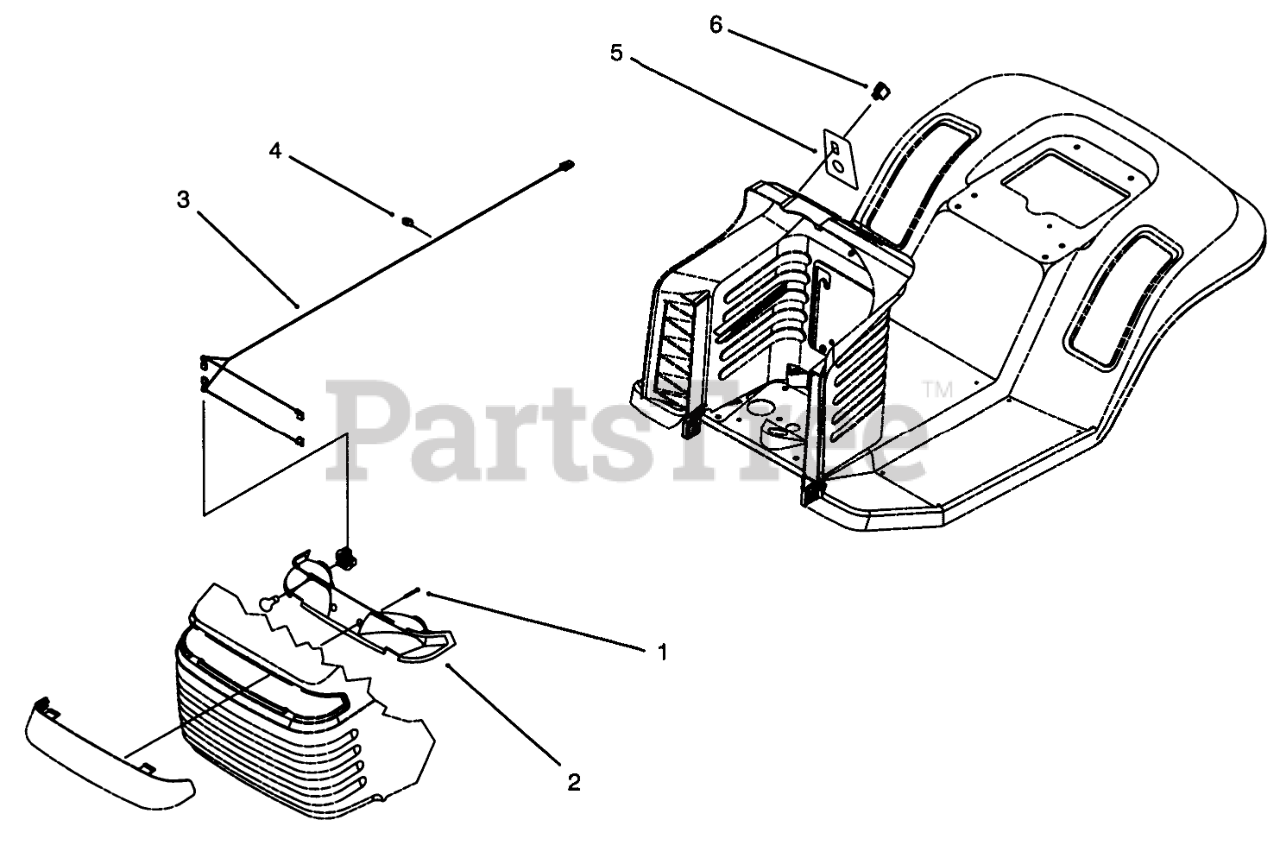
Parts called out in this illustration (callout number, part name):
2	HEADLIGHT REFLECTOR ASM
3	HARNESS-WIRE, LIGHTS
4	CLIP-RETAINER, WIRE
5	DECAL-IGNITION/LIGHTS
6	SWITCH-ROCKER
